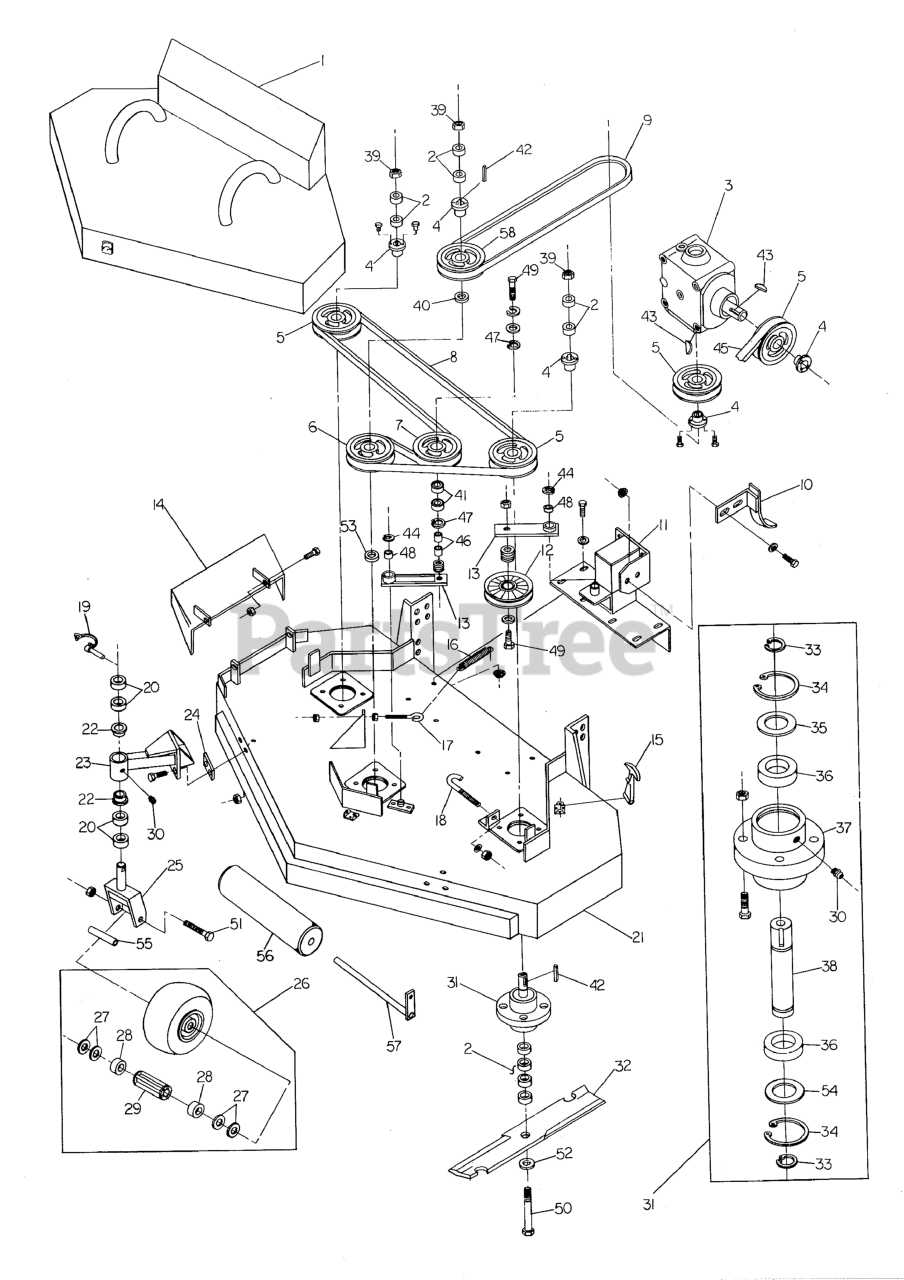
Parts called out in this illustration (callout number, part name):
1	48" DECK GUARD
1	61" DECK GUARD
2	SPACER, .63 x 1.06 x .23
3	Gear Box
4	BUSHING, Tapered Hub
5	PULLEY, Spindle
6	SPINDLE PULLEY
7	PULLEY, Idler
8	BELT, Blade Spindle
9	Belt 48" Deck
9	Belt 61" Deck
10	Belt Keep Weldment
11	Gearbox Support Weldment
12	PULLEY, Backside Idler
13	IDLER ARM
14	CHUTE, DISCHARGE WELDMENT
15	RUBBER LATCH
16	SPRING, Extension
17	EYEBOLT
19	PIN, Lynch
20	SPACER, 1.02 x 1.56 x .50
21	48" MOWER HOUSING
21	61" MOWER HOUSING
22	BUSHING, Flange
23	Caster Support
24	Caster Mount Spacer
25	YOKE, Caster
26	Caster Wheel Assembly
27	WASHER, 3/4 SAE
28	RETAINER, Bearing
29	BEARING, Roller
30	GREASE FITTING
31	SPINDLE ASSEMBLY, Complete
32	MOWER BLADE, 16-1/4"
32	MOWER BLADE, 21"
33	SNAP RING, External
34	SNAP RING, Internal
35	SPINDLE WASHER, Top
36	BEARING
37	SPINDLE HOUSING
38	SPINDLE SHAFT
39	NUT, 5/8-11 Hex
40	Center Spindle Spacer
41	BEARING, BALL 11/16X1-9/16X15/32
42	KEY, 1/4 SQ. X 2-1/2
43	Woodruff Key
44	C-CLIP
46	INSERT, Bearing
47	SNAP RING, Internal
48	BUSHING, Brass
49	1/2-20 x 2-1/4 Bolt
50	BOLT, 5/8-11 x 9-1/2
51	1/2-13 x 5-1/2 Bolt
52	5/8 Washer
53	SPACER, 1.00 X 1.25 X .25
54	SPINDLE WASHER, Bottom
55	AXLE, Caster Wheel
56	ROLLER
58	PULLEY, Spindle
